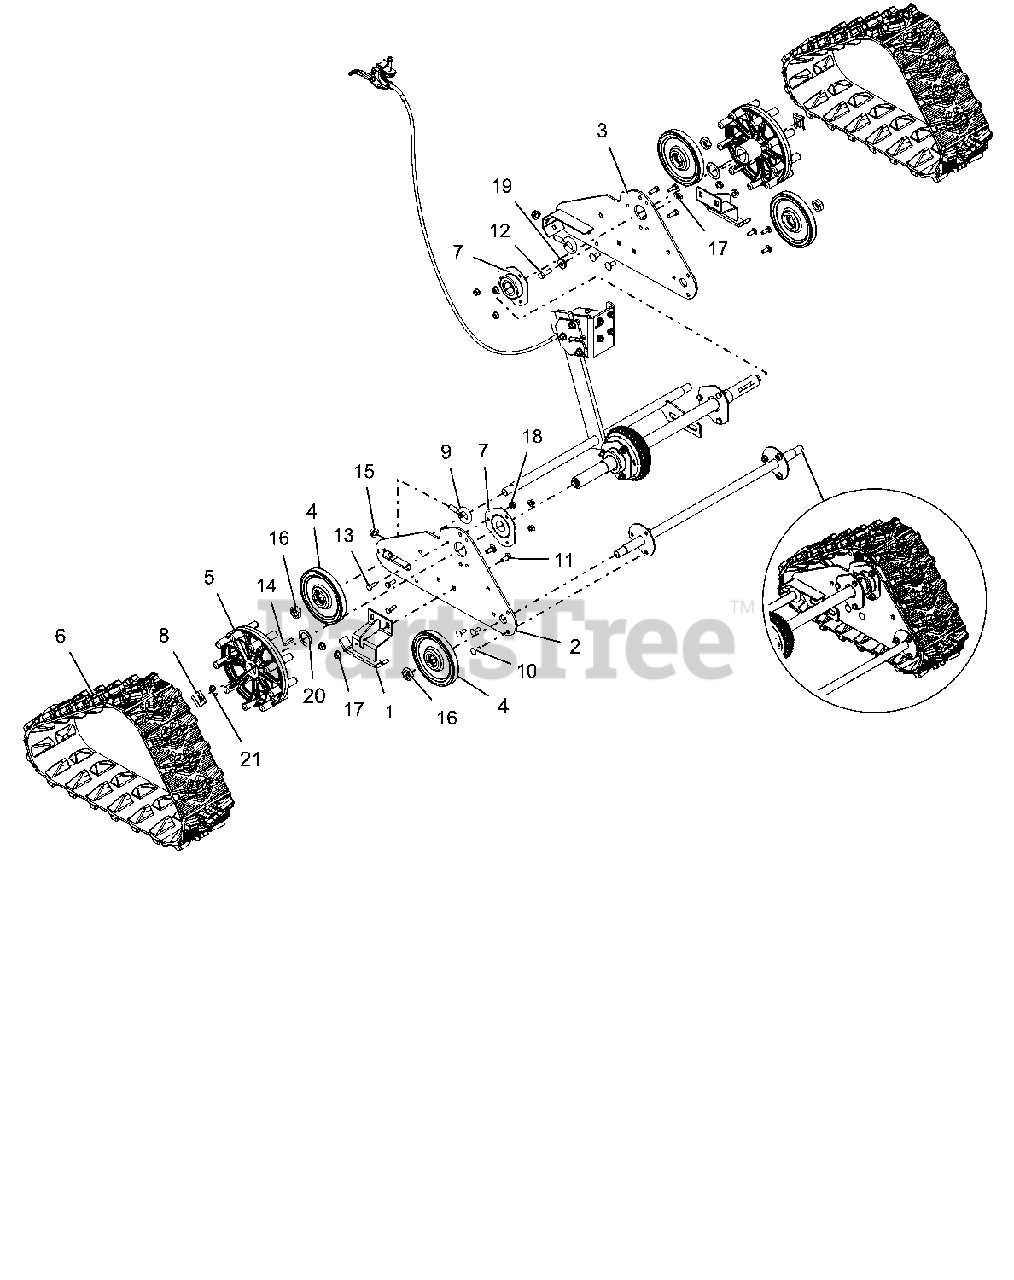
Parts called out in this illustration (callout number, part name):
1	RUNNER, GUIDE-TRACK
2	SIDE PLATE, RH-TRACK
3	SIDE PLATE, LH-TRACK
4	WHEEL, BOGIE - SINGLE BEARING
5	WHEEL, MACHINED DRIVE
6	TRACK, RUBBER
7	BRG-FLG 1.003/1.000 3 BOLT
8	CLIP, SNAP .625 DIA
9	BLT-EYE .375-16X.880 YWZC
10	@BLT-RDHDSQNK .25-20X.75 G5YZ
11	@BLT-RDHDSQNK .31-18X.75 G5YZ
12	@BLT-HEX .25-20X.75 GR5 YWZC
13	@BLT-HEX .25-20X.75 GR5 YWZC
14	KEY-RECT .25X.188X1.00
15	@NUT-LK-CTR-FLG .25-20 YWZC
16	@NUT-LK-NYL .625-18 YWZC
17	@NUT-LK-TOP-FLG .31-18 YWZC
18	@NUT-LK-TOP-FLG .25-20 YWZC
19	BSHG-FLG .325X.499X.3X.875
20	WSHR-FL-STL 1.010X1.505X.062YZ
21	RG-RTNG-EXT .625X.042
